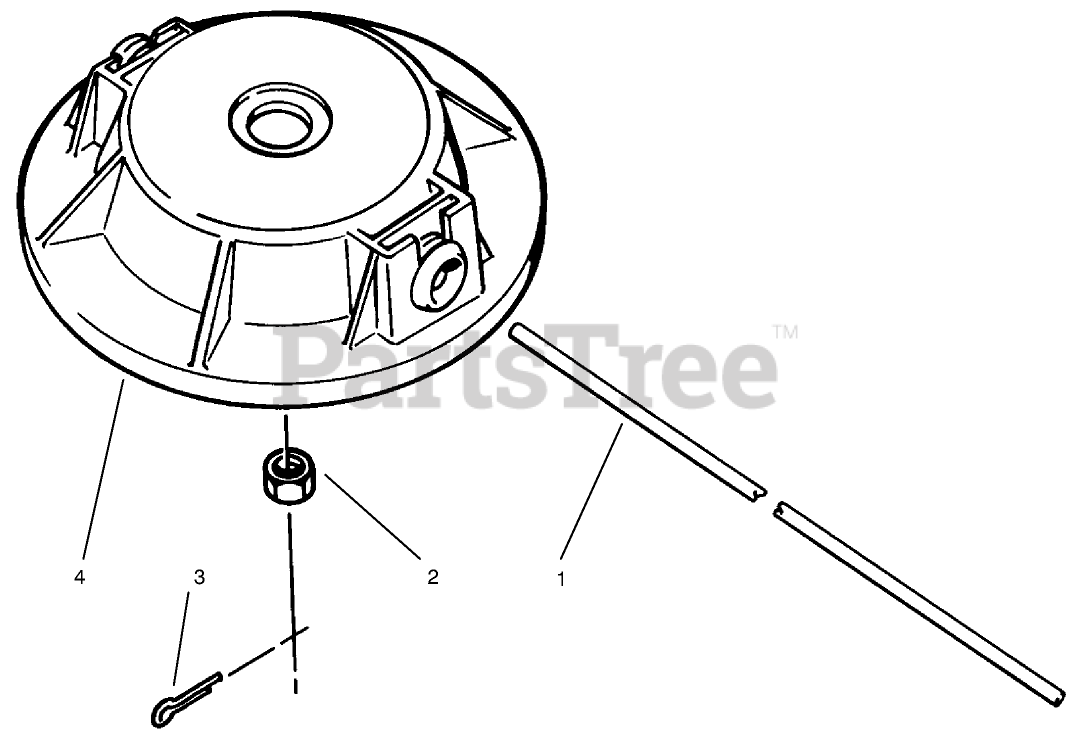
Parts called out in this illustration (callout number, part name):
1	Line-Cutting
3	1/16 X 1 LG COTTER PIN
4	CUTTER HEAD-PLASTIC
